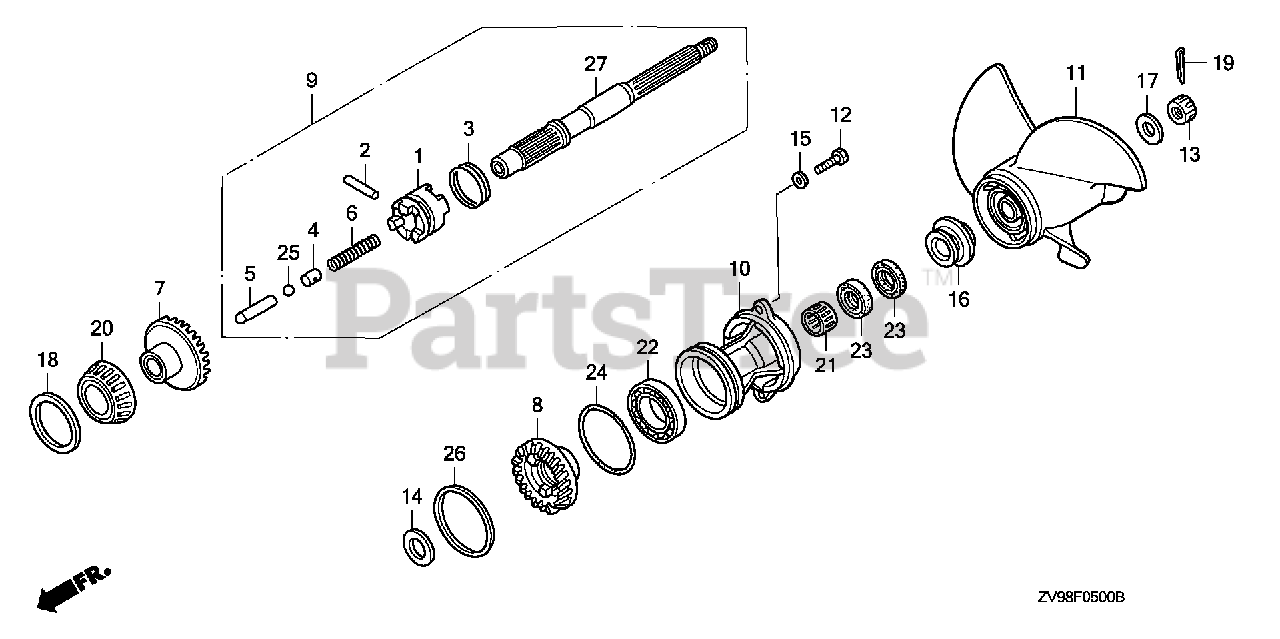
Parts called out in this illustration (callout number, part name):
1	SHIFTER, CLUTCH
2	PIN, SHIFTER
3	RING, CROSS PIN
4	HOLDER, SHIFTER PIN
5	SLIDER, SHIFT
6	SPRING, SHIFT
7	GEAR, FR. BEVEL
8	GEAR, RR. BEVEL
9	SHAFT ASSY., PROPELLER
10	HOLDER, PROPELLER SHAFT *NH282MU* (OYSTER SILVER METALLIC-U)
11	PROPELLER, THREE-BLADE (9-1/4X12) (91X120) *NH283* (STIN GRAY)
11	PROPELLER, THREE-BLADE (9-3/4X9-7/8) (98X99) *NH283* (STIN GRAY)
11	PROPELLER, THREE-BLADE (10X8-1/4) (100X83) *NH283* (STIN GRAY)
12	BOLT, HEX. (6X20)
13	NUT, CASTLE
14	WASHER (22MM)
15	WASHER, PLAIN (6MM)
16	WASHER, PROPELLER THRUST
18	SHIM, FR. BEVEL (51X57X0.10) (A)
18	SHIM, FR. BEVEL (51X57X0.15) (B)
18	SHIM, FR. BEVEL (51X57X0.30) (C)
18	SHIM, FR. BEVEL (51X57X0.50) (D)
19	PIN, SPLIT
20	BEARING (32X58X17)
21	BEARING, NEEDLE (22X28X20)
22	BEARING, RADIAL BALL (32X58X13) (KOYO)
23	SEAL, WATER (22X35X7)
24	O-RING (64X3)
25	BALL, STEEL (#11) (11/32)
26	SHIM, FR. BEVEL (51X57X0.10) (A)
26	SHIM, FR. BEVEL (51X57X0.15) (B)
26	SHIM, FR. BEVEL (51X57X0.30) (C)
26	SHIM, FR. BEVEL (51X57X0.50) (D)
27	SHAFT, PROPELLER
